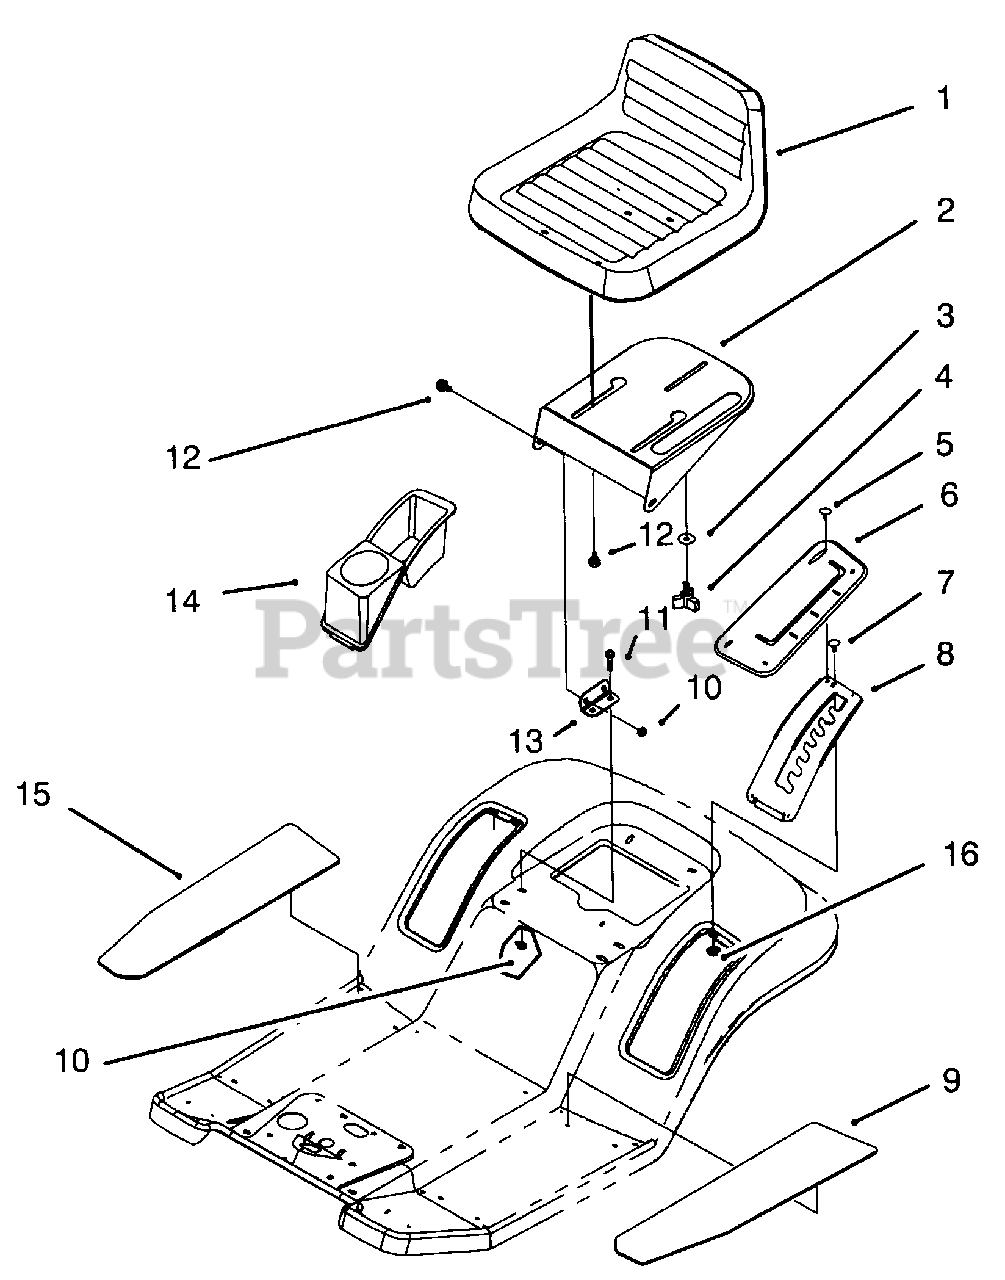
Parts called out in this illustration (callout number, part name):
1	Seat
2	Support-Seat
3	Washer-Fender
4	Knob-Studded
6	Cover-H.O.C.
7	Rivet-Pop
8	Gate-H.O.C.
9	Tread-L.H. Foot
10	Nut-Lock
11	Screw-Hex Hd. Cap
12	Bolt-Shoulder
13	Bracket-Seat Hinge
14	Tray-Fender
15	Tread-R.H. Foot Hydro
16	Washer-Backup
